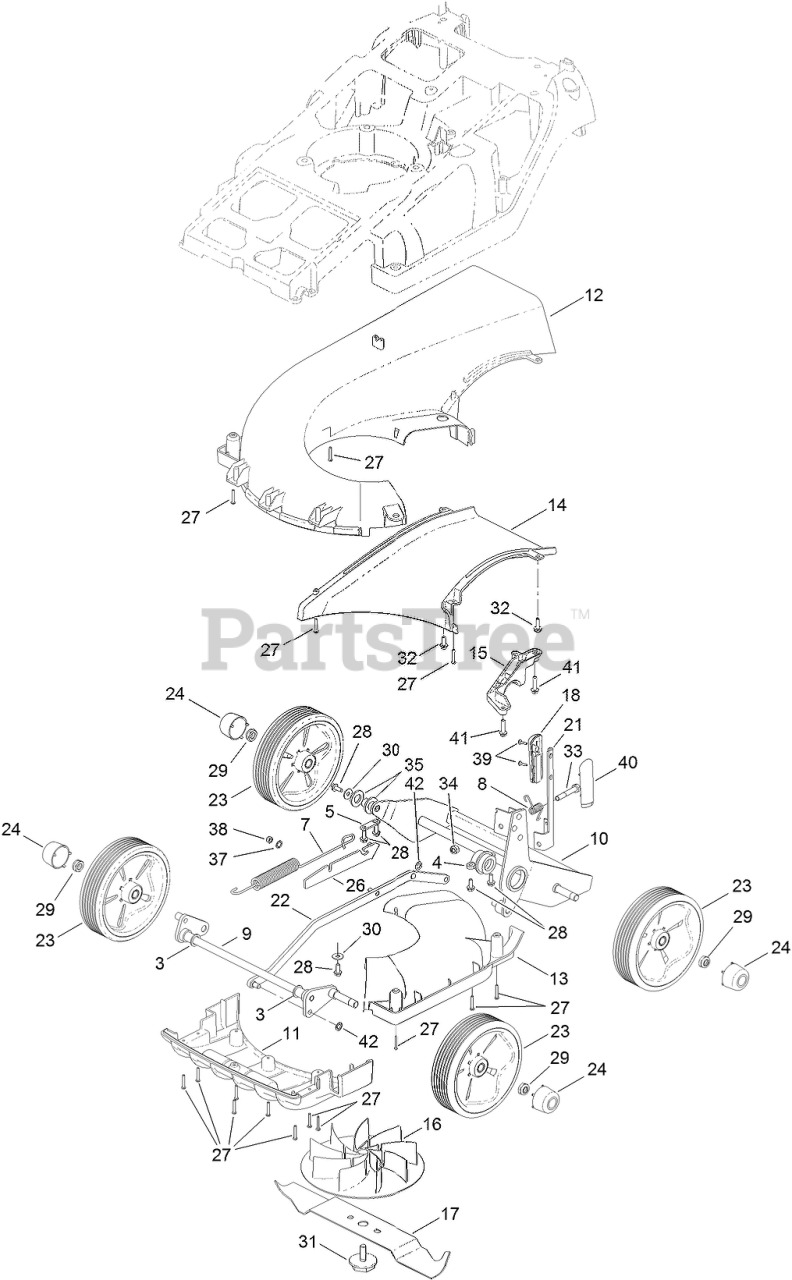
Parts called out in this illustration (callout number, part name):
3	BEARING-AXLE, FRONT
4	HOUSING-PIVOT BEARING, LH
5	PLATE-SECURING
7	SPRING-COUNTER BALANCE
8	SPRING-HOC
9	AXLE-FRONT
10	FRAME-WHEEL
11	MOULDING-FIN
12	MOULDING-SNAIL DECK
13	MOULDING-ACCESS, SNAIL DECK
14	MOULDING-THROW PLATE
15	MOUNT-BEARING
16	MOULDING-MOUNT, ELECTRIC BLADE
17	CUTTERBAR-ELECTRIC
18	KNOB-HOC, RH
21	LEVER-HOC
22	ROD-CONNECTING BAR
23	WHEEL ASM
24	CAP-WHEEL, CENTER
26	MOUNT-SPRING
28	SCREW M6 X 16 TAPTITE HEX HD
29	NUT-NYLOC
30	WASHER
31	BOLT-FIXING, BLADE
32	SCREW-TAPTITE
33	SCREW-HH
34	NUT-HEX, NI
35	WASHER-PLAIN
37	WASHER-SHAKEPROOF
38	NUT-NYLOC
40	KNOB-HOC, LH
41	SCREW-TAPTITE
42	WASHER-STARLOCK
